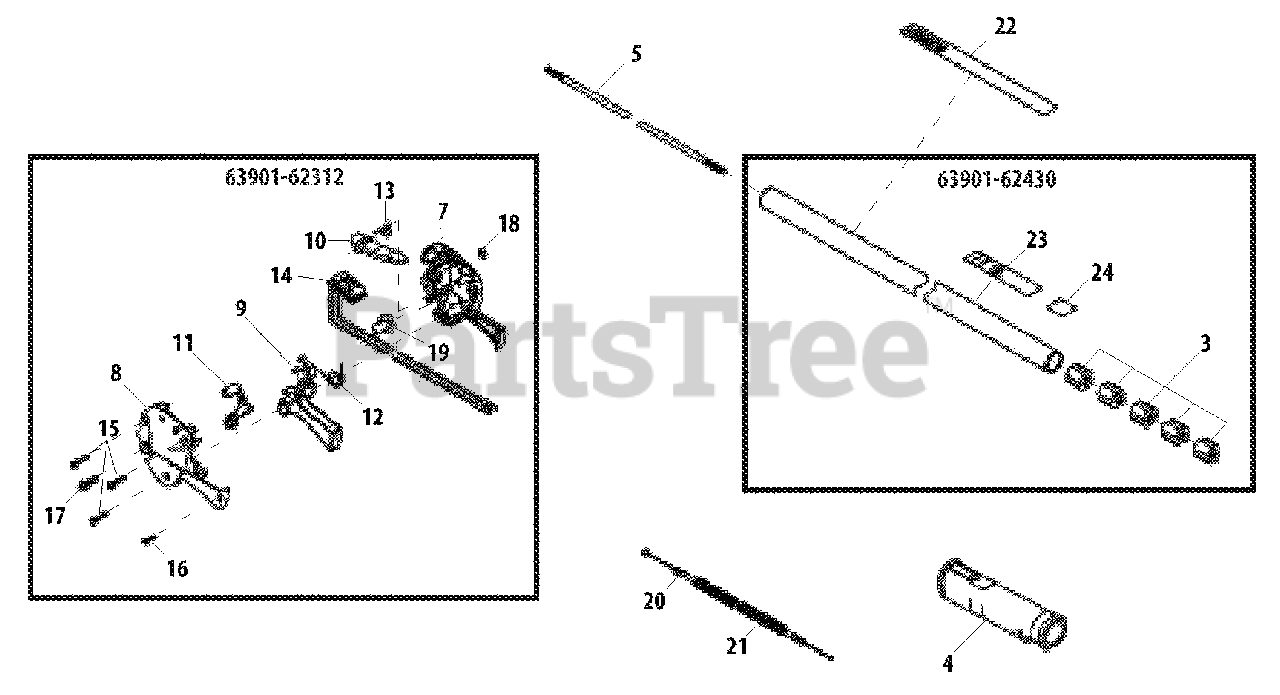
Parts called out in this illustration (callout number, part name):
3	BUSHING
4	GRIP
5	PIPE, MAIN
7	HANDLE, CONTROL - RIGHT
8	HANDLE, CONTROL - LEFT
9	LEVER
10	LEVER, LOCK
11	HOLDER
12	SPRING
13	SPRING
14	SWITCH, IGNITION
15	SCREW - 4X20 -- TAPPING
16	SCREW - 3X14 -- TAPPING
17	SCREW - 5X20
18	NUT - 5
19	PLUG
20	CABLE, THROTTLE
21	TUBE
22	LABEL - TRADE
23	LABEL - CAUTION
24	LABEL - INSTRUCTION
63901-62312	THROTTLE LEVER ASSY
63901-62430	MAIN PIPE ASSY
